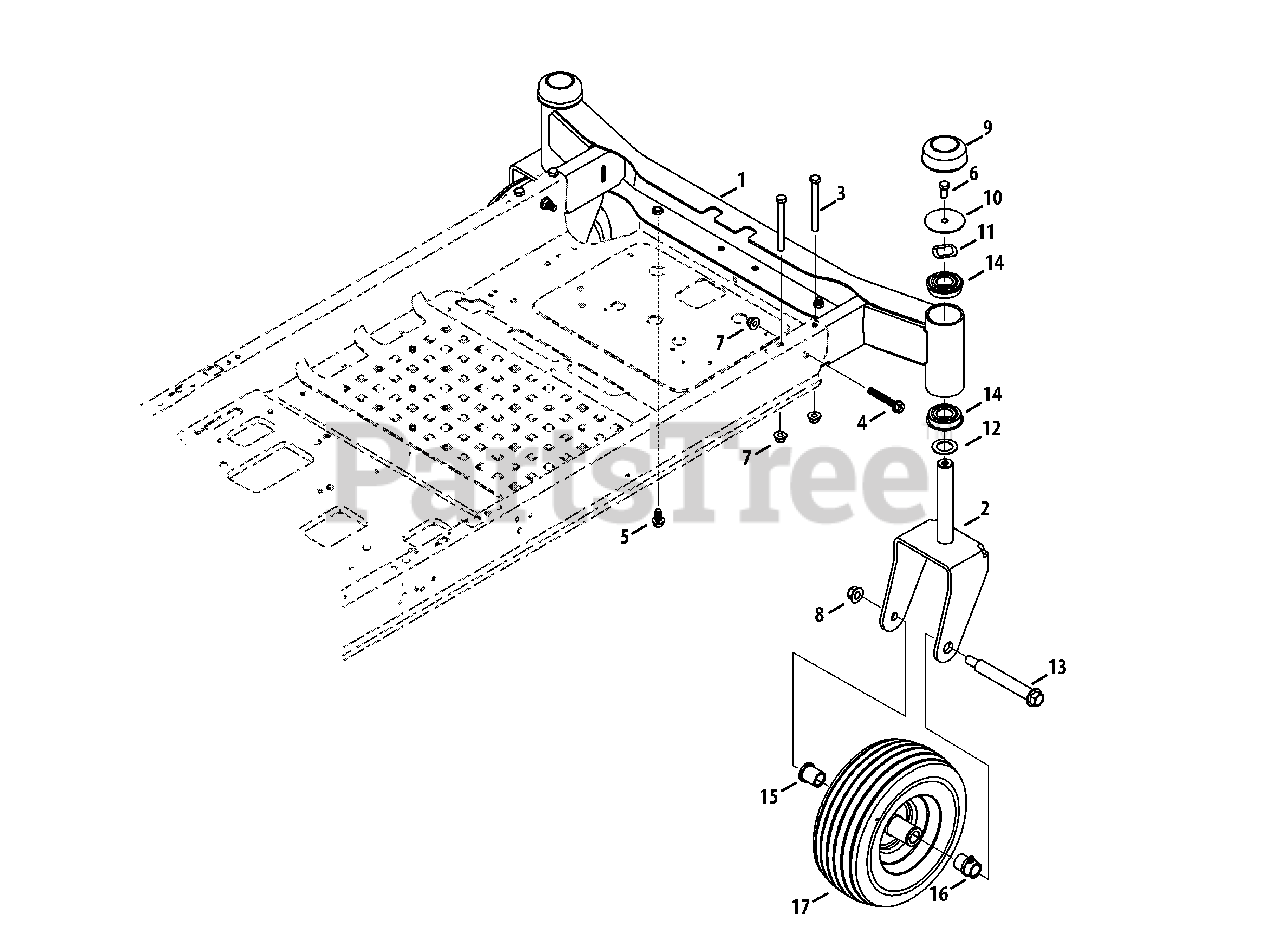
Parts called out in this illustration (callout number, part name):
2	Caster Wheel Bracket
3	Hex Cap Screw, 3/8-16 x 3.75
4	Hex Flange Screw, 3/8-16 x 2.25
5	Screw TT, 3/8-16 x .750
6	Hex Cap Screw, 3/8-16 x .750
7	Flange Lock Nut, 3/8-16
8	Flange Lock Nut, 1/2-13
10	Flat Washer, .406 x 2.50 x .060
11	Wave Washer, 1.25 x 1.00 x .300
12	Flat Washer, 1.010 x 1.56 x .060
13	Shoulder Screw, 1/2-13
14	Ball Bearing
15	Flange Bearing, .76 x 1.0 x 1.2
16	Flange Bearing, .76 ID w/Lube Ftg.
17	Wheel Assembly, 11.0 x 4.0 x 5.0
